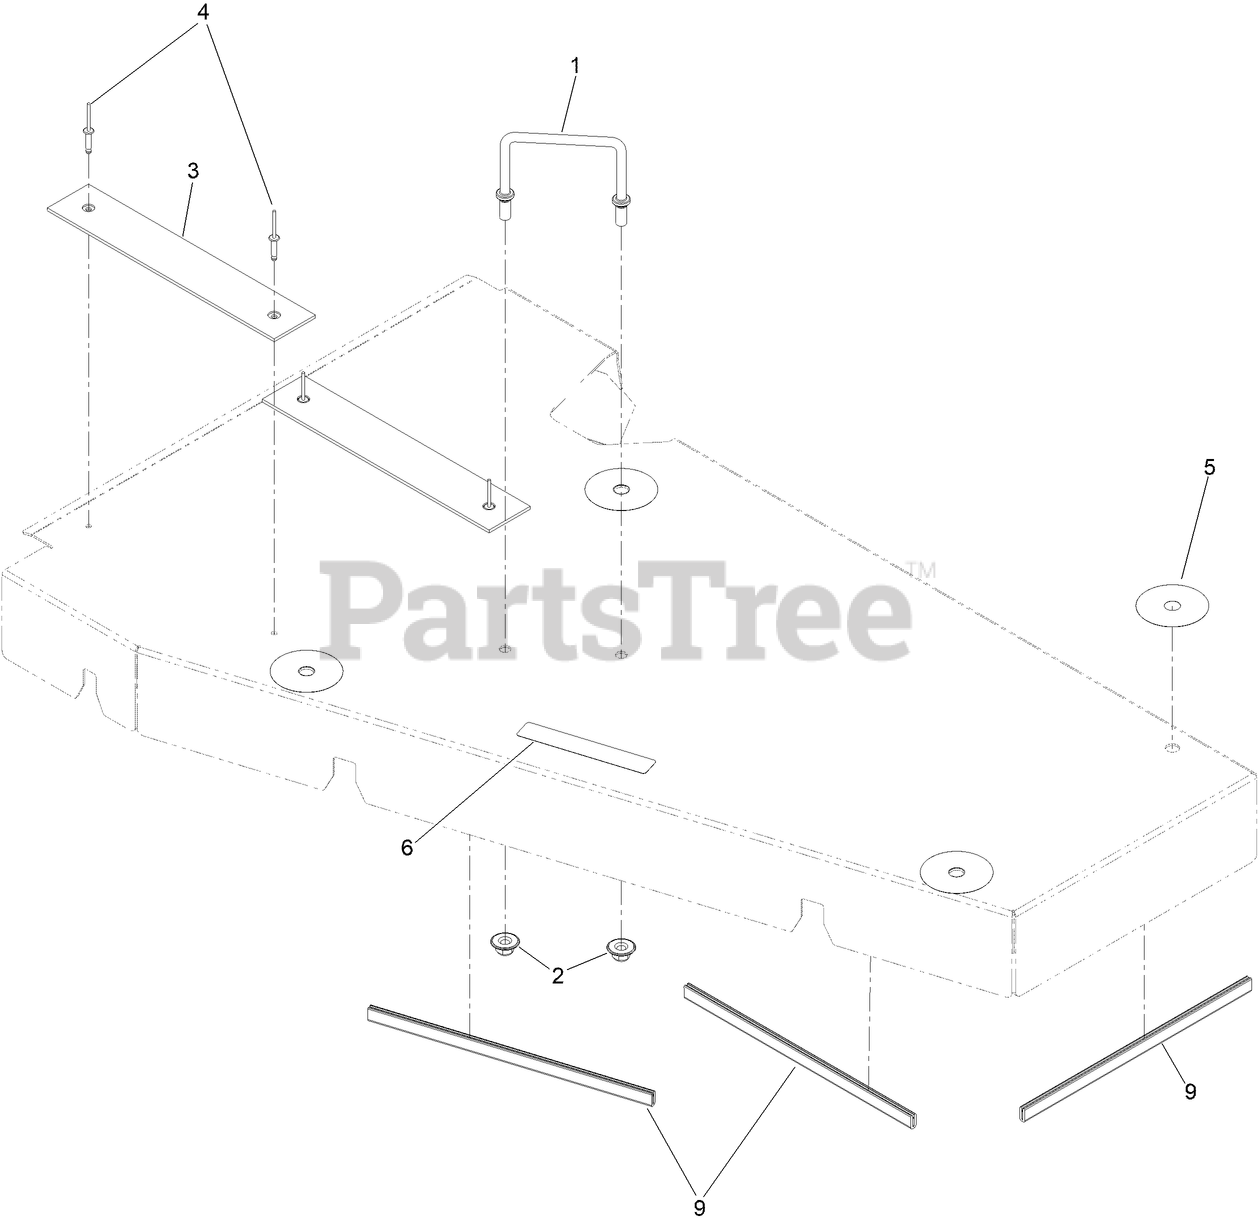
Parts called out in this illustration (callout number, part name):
1	WIREFORM-COVER
2	Nut-Nyloc 3/8-16 Flg
3	Plate-Uhmw 2"
4	Rivet-Pop
5	DECAL-SCRATCH COVER
6	DECAL-NO STEP
9	GUARD-EDGE
